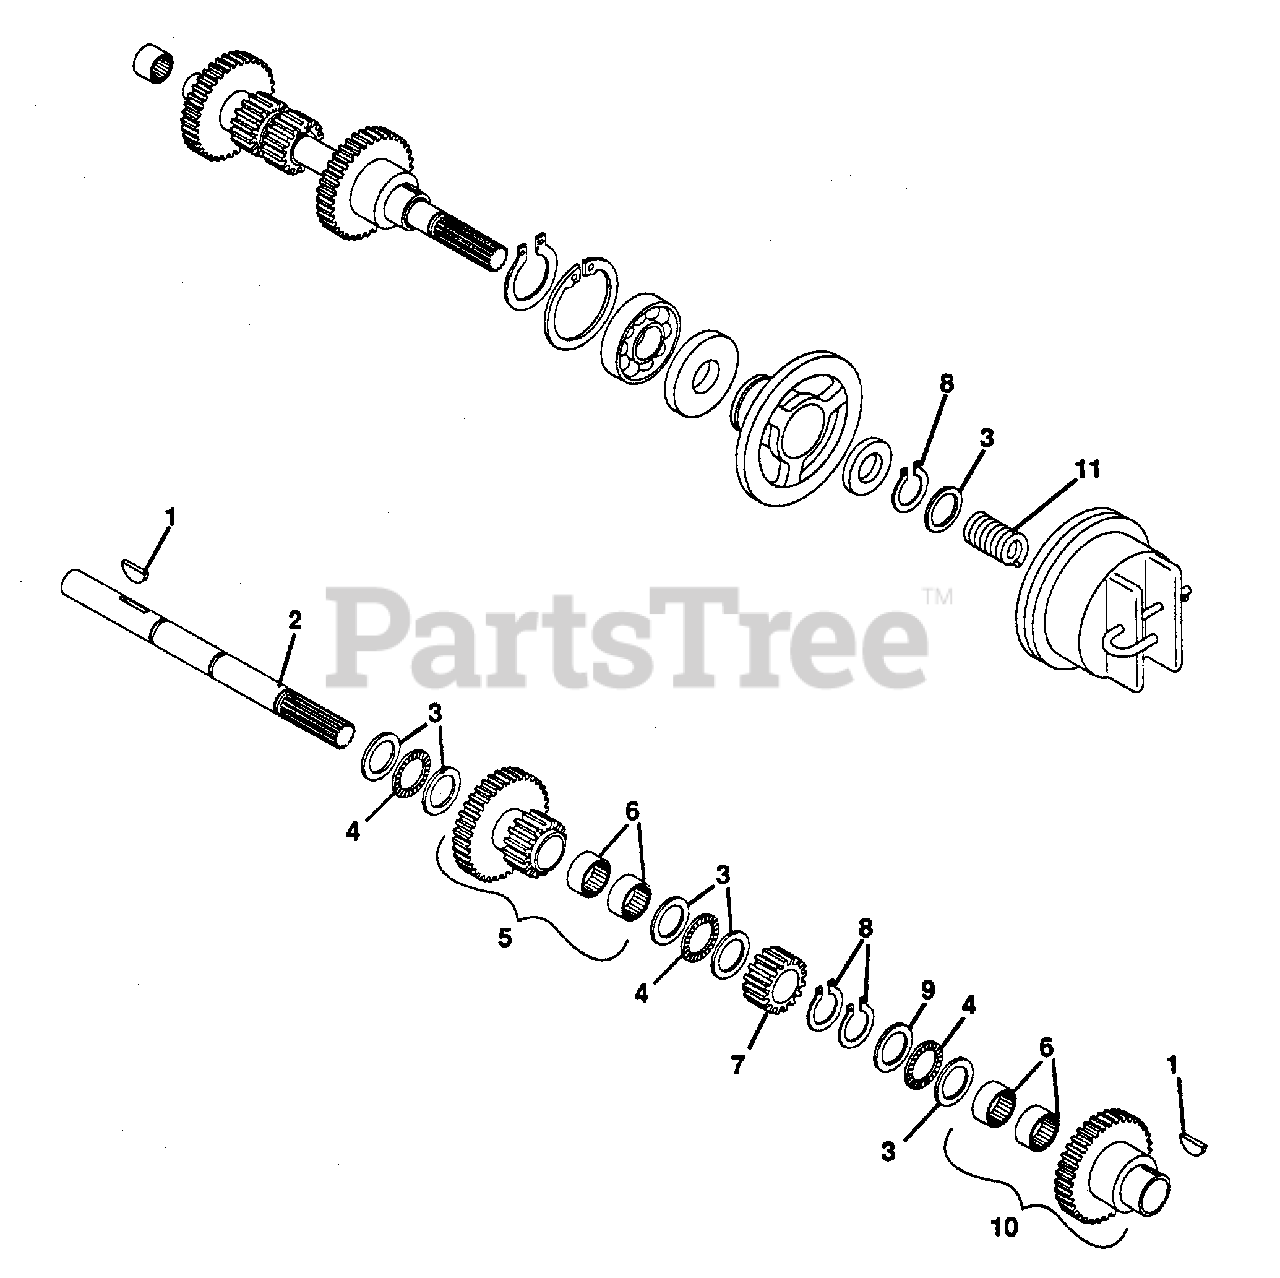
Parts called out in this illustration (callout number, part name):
1	KEY, WOODRUFF .188X.625 HRD #61
2	SHAFT, SPLINED REV CLUTCH
3	RACE, BRG THRUST .752X1.240X.030
4	BRG, NEEDLE THRUST .752X1.24X.078
5	GEAR, IDLER ASSEMBLY
6	BEARING, NEEDLE .75X1X.50
7	GEAR, 10 DP 16 TEETH X .750 STD.
8	RING, RETAINING .750 SHAFT
9	RACE, .060 BEARING THRUST
10	ASSEMBLY, REVERSE GEAR AND BRG
11	SPRING, COMP. 1.0X.80X36 LB/IN
